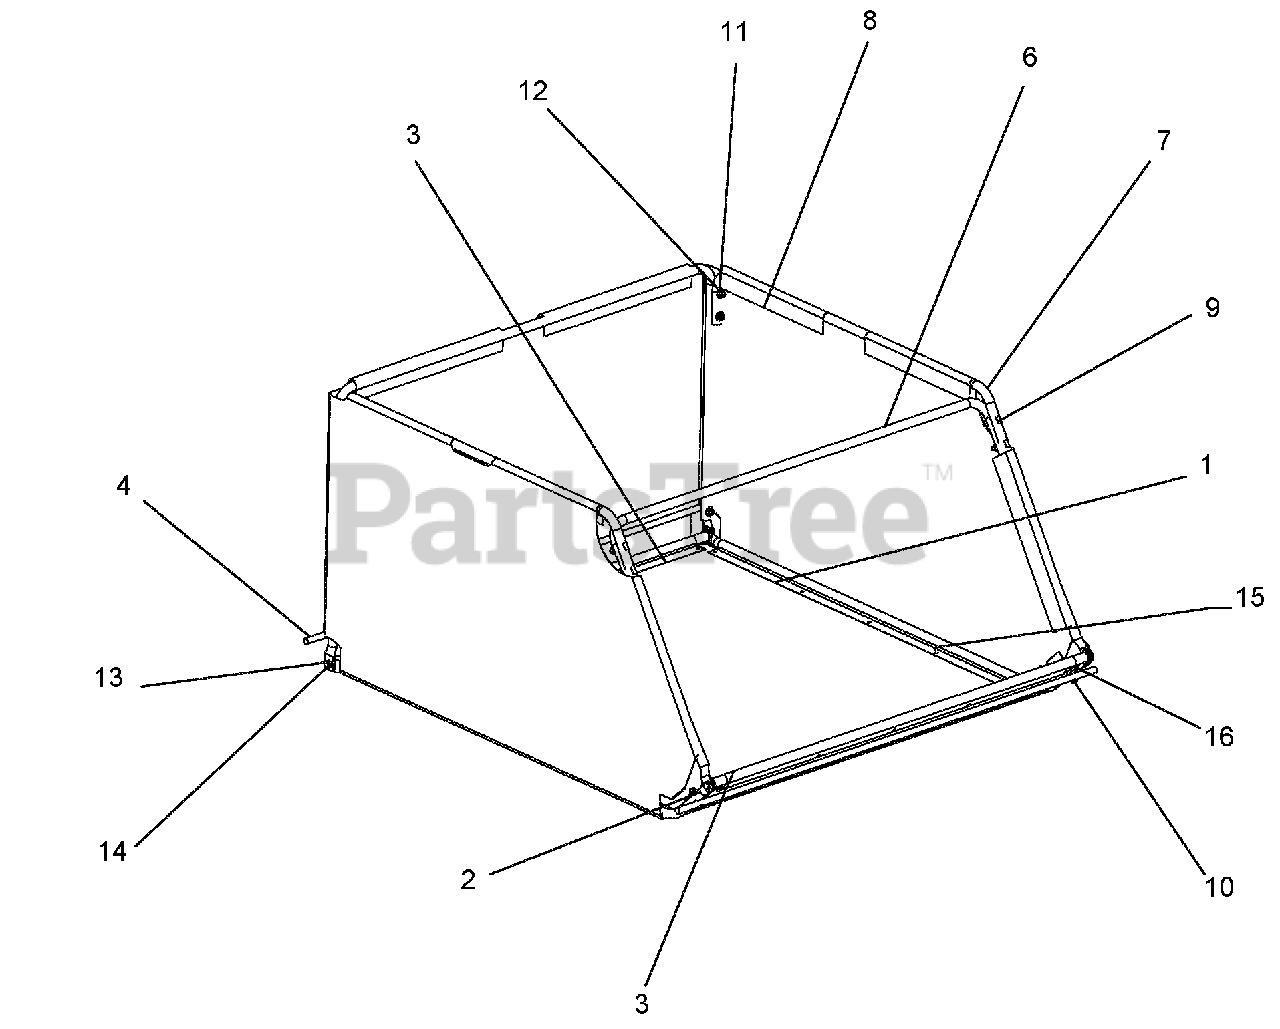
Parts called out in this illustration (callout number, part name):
1	Basket Clamp Assembly
2	Basket Clamp Assembly
3	Basket Clamp Assembly
4	Support Rod
5	Rear Upright
6	Front Upright
7	Frame Basket Side Top
8	Basket Assembly
9	Bolt, 1/4-20 x 2.0 Contour Hd.
10	Bolt, 1/4-20 x 1.5 Hex 5
11	Washer, .312 x .734 x .065 Flat
12	Nut, Hex 1/4-20
13	Washer, 5/16 Spring Lock
14	Bolt, 5/16-18 x 1.00 Hex 5
15	Rivet, Bulb Tite
16	Basket Bottom, Mesh
17	Basket Bottom, Solid
